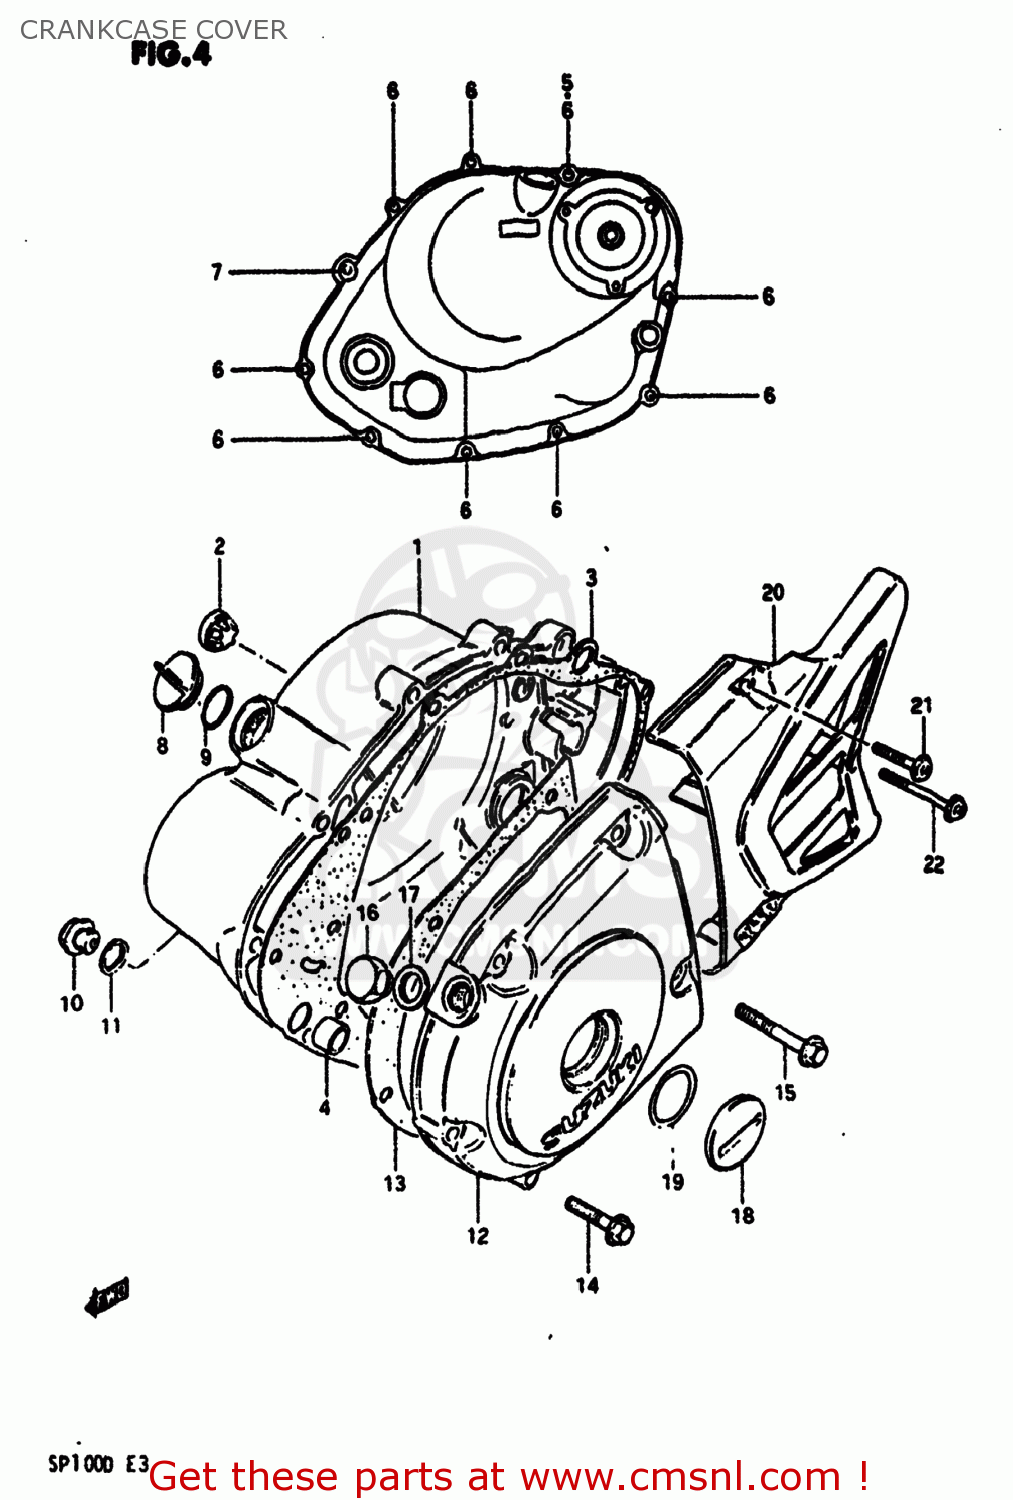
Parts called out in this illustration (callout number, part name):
1	COVER,CLUTCH
2	LENS,OIL LEVEL CHECK
3	GASKET,CLUTCH COVER (MCA)
4	PIN
5	GASKET (NAS)
6	BOLT (6X30)
7	BOLT
8	PLUG
9	O RING(D:3.1,ID:16.8)
10	PLUG (14X12)
11	GASKET(14X19.2X2) (NAS)
12	COVER,MAGNETO
13	GASKET,MAGNETO COVER (MCA)
14	BOLT (6X30)
15	BOLT (6X40)
16	PLUG,12X9
17	GASKET(12.1X16.2X3.7) (NAS)
18	PLUG
19	O RING(D:3.1,ID:22.7)
20	COVER,SPROCKET
21	BOLT
22	BOLT
